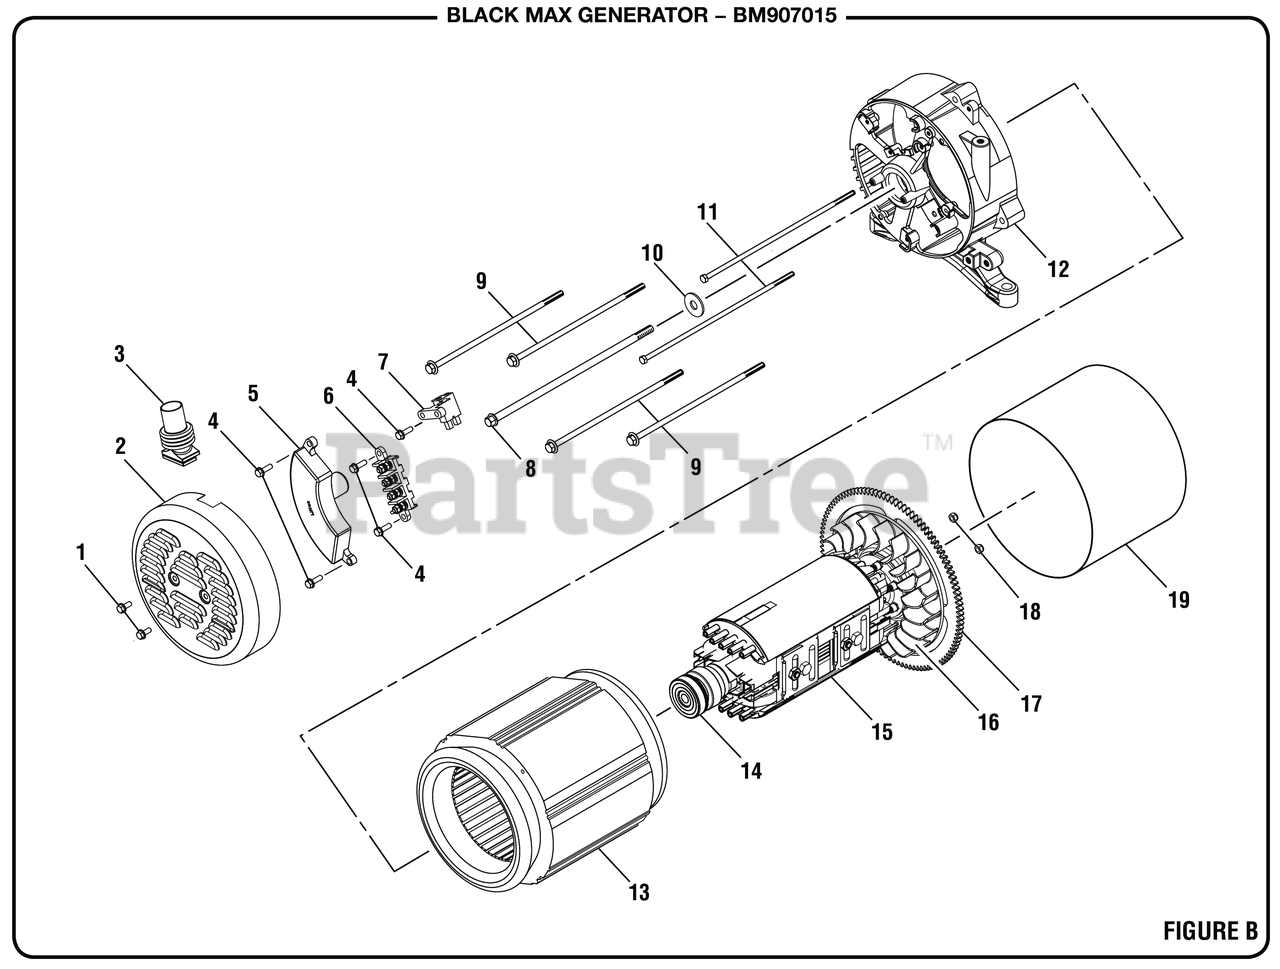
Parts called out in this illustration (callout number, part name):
1	Bolt (M5 x 12 mm, Hex Flange Hd.)
2	Brush Cover
3	Rubber Boot
4	Bolt (M5 x 16 mm, Hex Flange Hd.)
5	Automatic Voltage Regulator (5000 Watt)
6	Terminal Block
7	Brush Assembly 190 mm
8	Bolt (5/16-24 x 235 mm, Hex Washer Hd.)
9	Bolt (M6 x 188 mm, Hex Washer Hd.)
10	Washer (ID10 x OD28 x 3t)
11	Bolt (M5 x 210 mm, Hex Washer Hd.)
12	Bearing Housing'
13	Stator Assembly
14	Ball Bearing (190 mm)
15	Rotor Assembly
17	Starter Gear
18	Hex Nut (M5)
19	Generator Head Cover
